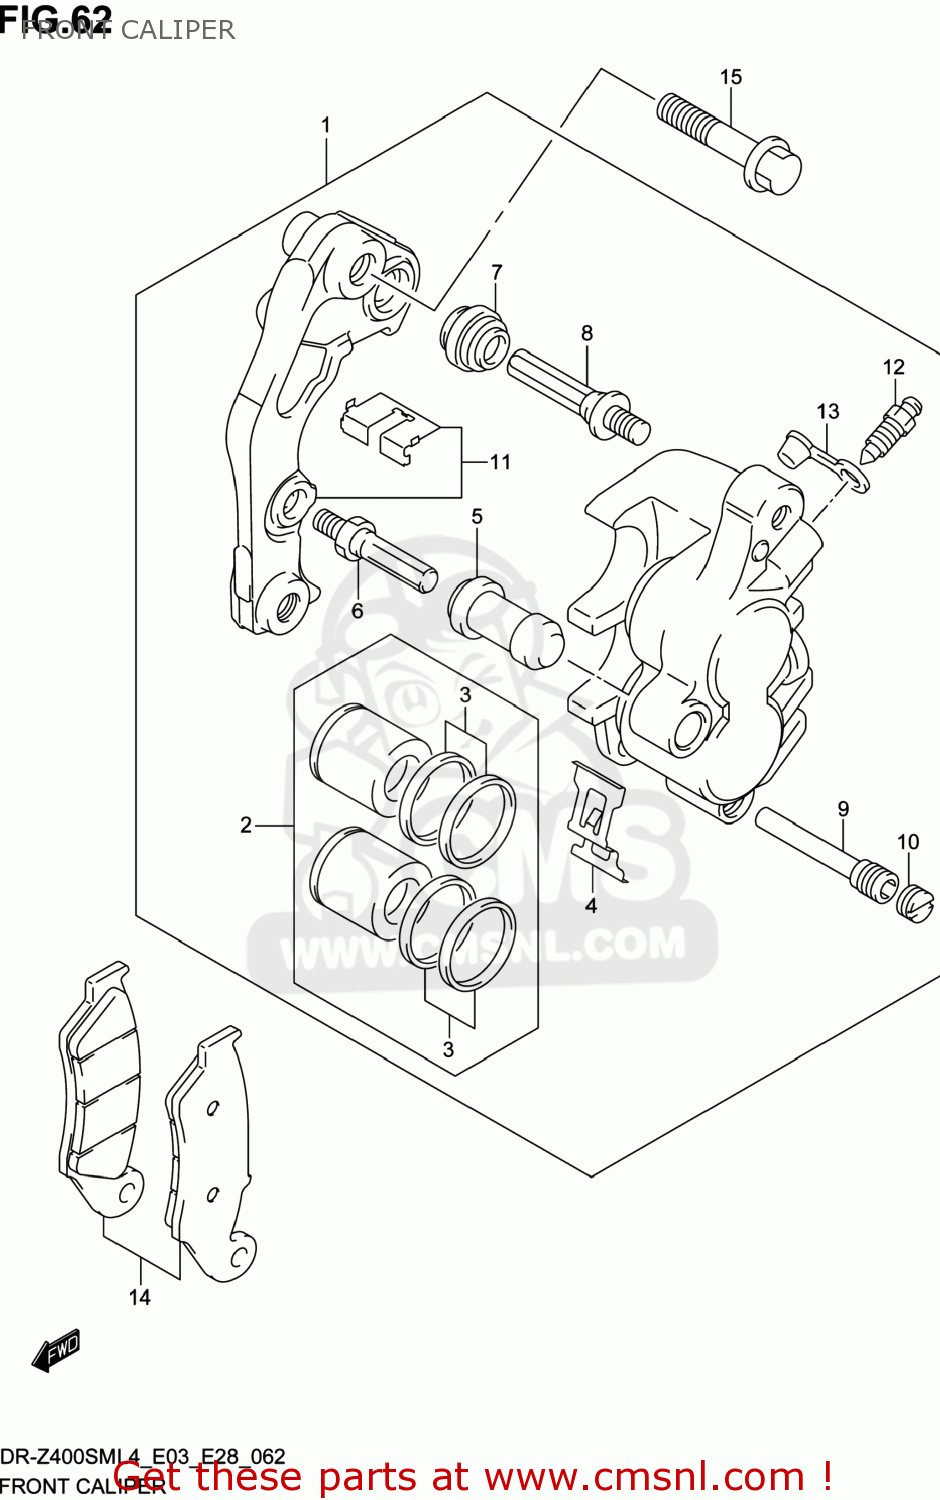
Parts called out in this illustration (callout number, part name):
1	CALIPER ASSY,FR,L
2	PISTON SET
3	SEAL SET,PISTON
4	SPRING,PAD
5	BOOT
6	PIN,BOLT
7	BOOT
8	PIN
9	PIN,HANGER
10	PLUG,PIN
11	BRACKET
12	BLEEDER
13	CAP,BLEEDER
14	PAD SET (NAS)
15	BOLT(8X40)
